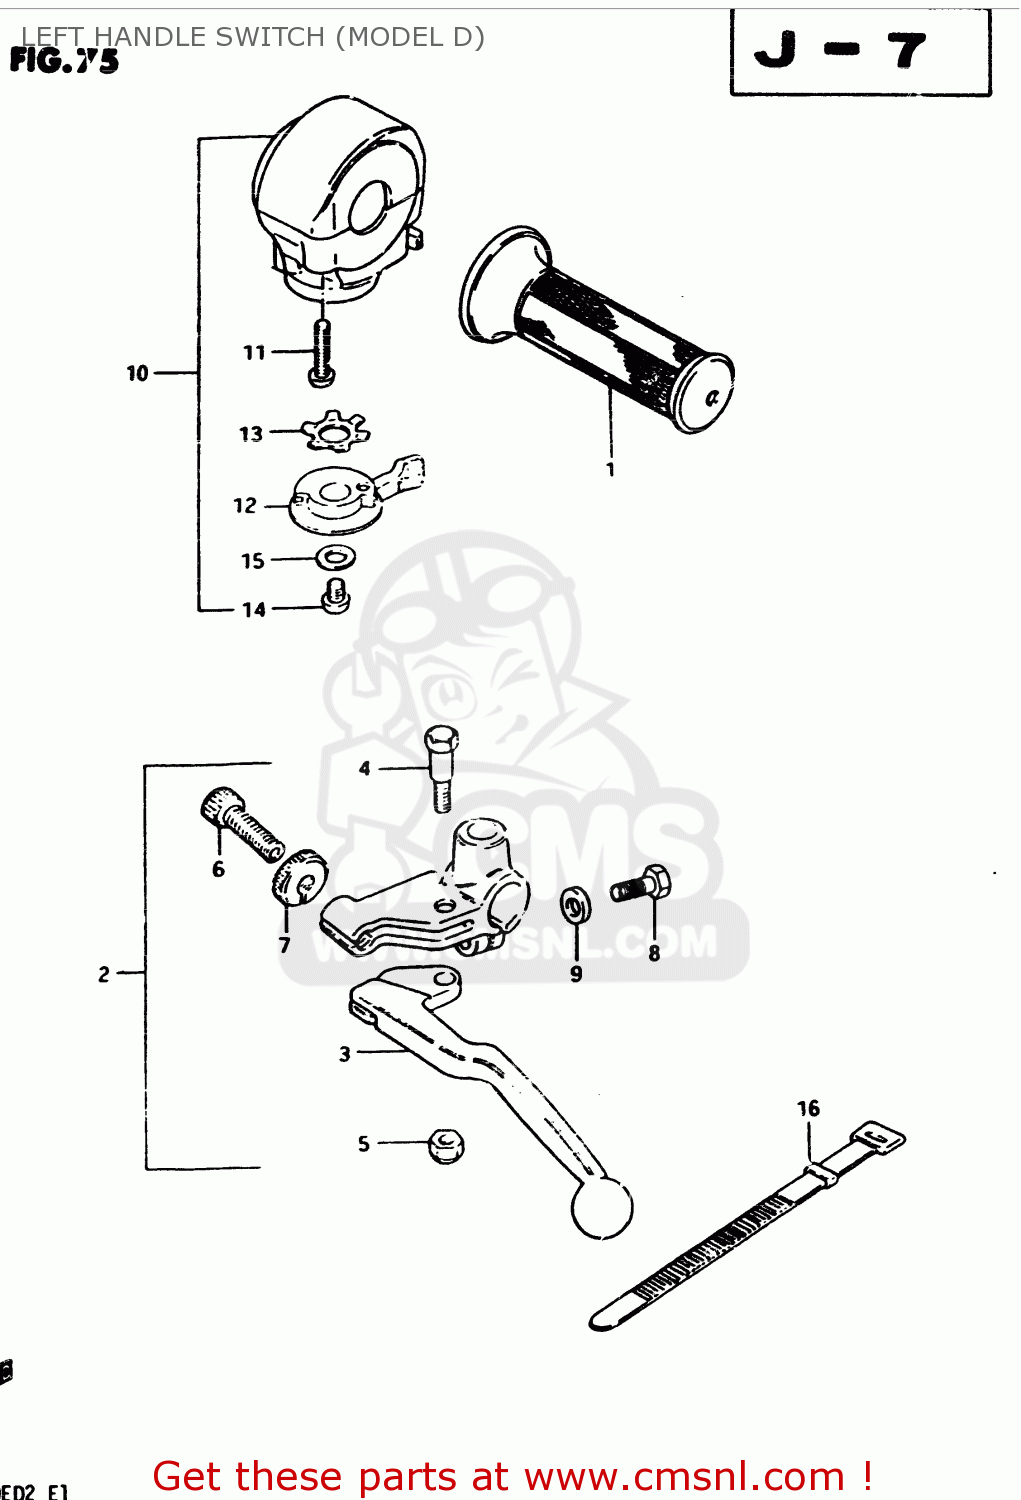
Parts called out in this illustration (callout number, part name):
1	GRIP,L
2	LEVER ASSEMBLY,CLUTCH
3	LEVER,CLUTCH
4	BOLT,LEVER PIVOT
5	NUT 6MM
6	ADJUSTER,CABLE
7	NUT,CABLE ADJUSTER LOCK
8	BOLT,CLUTCH LEVER HOLDER
9	WASHER
10	SWITCH ASSY, HANDLE LH
11	SCREW
12	LEVER,STARTER
13	WASHER
14	SCREW
15	WASHER 6MM
16	CLAMP(L:120)
